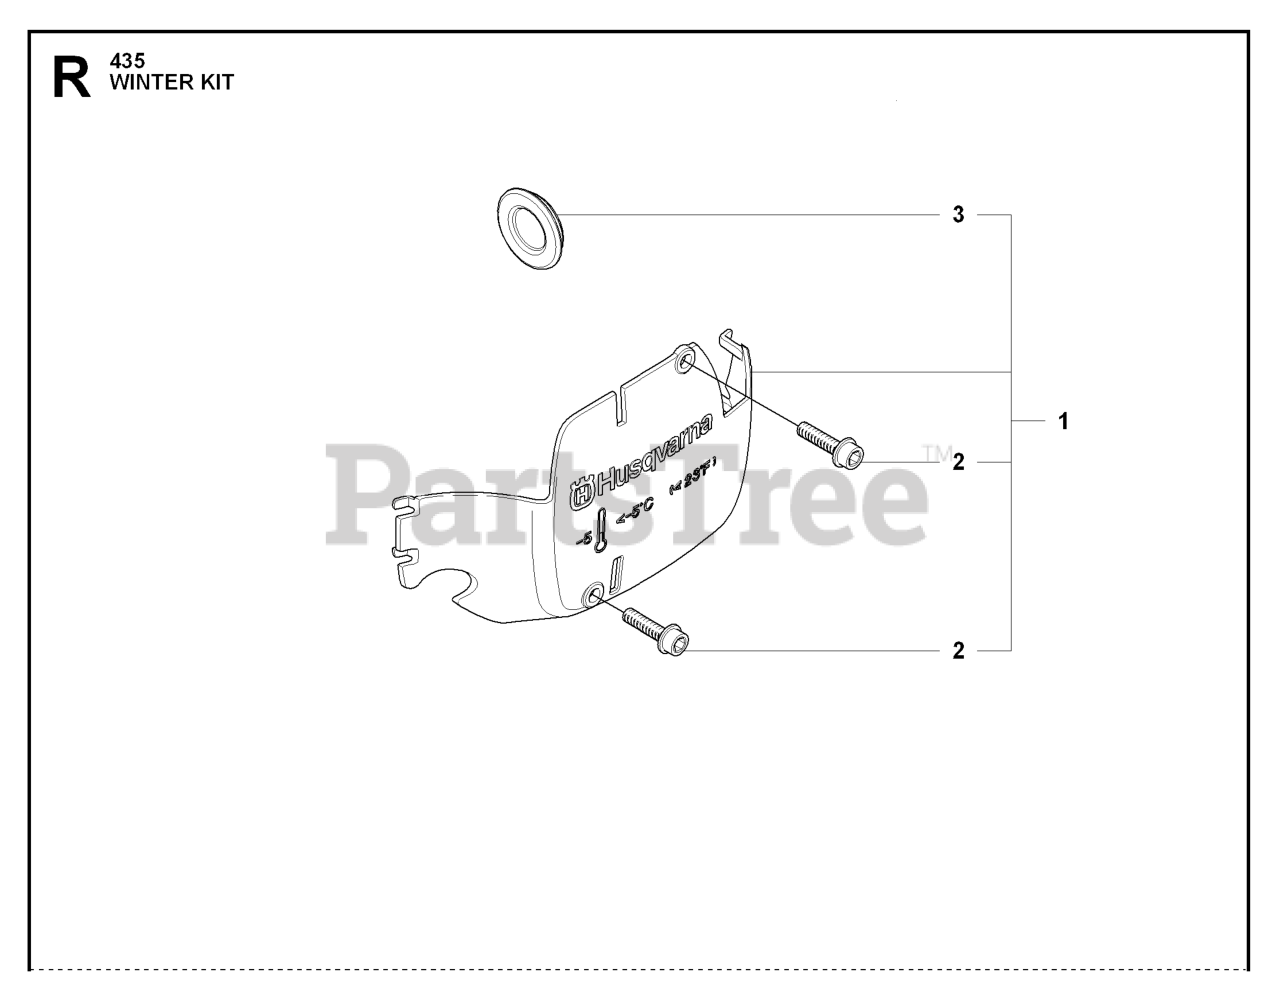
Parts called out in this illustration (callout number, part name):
1	WINTER KIT
2	SCREW
3	PLUG
